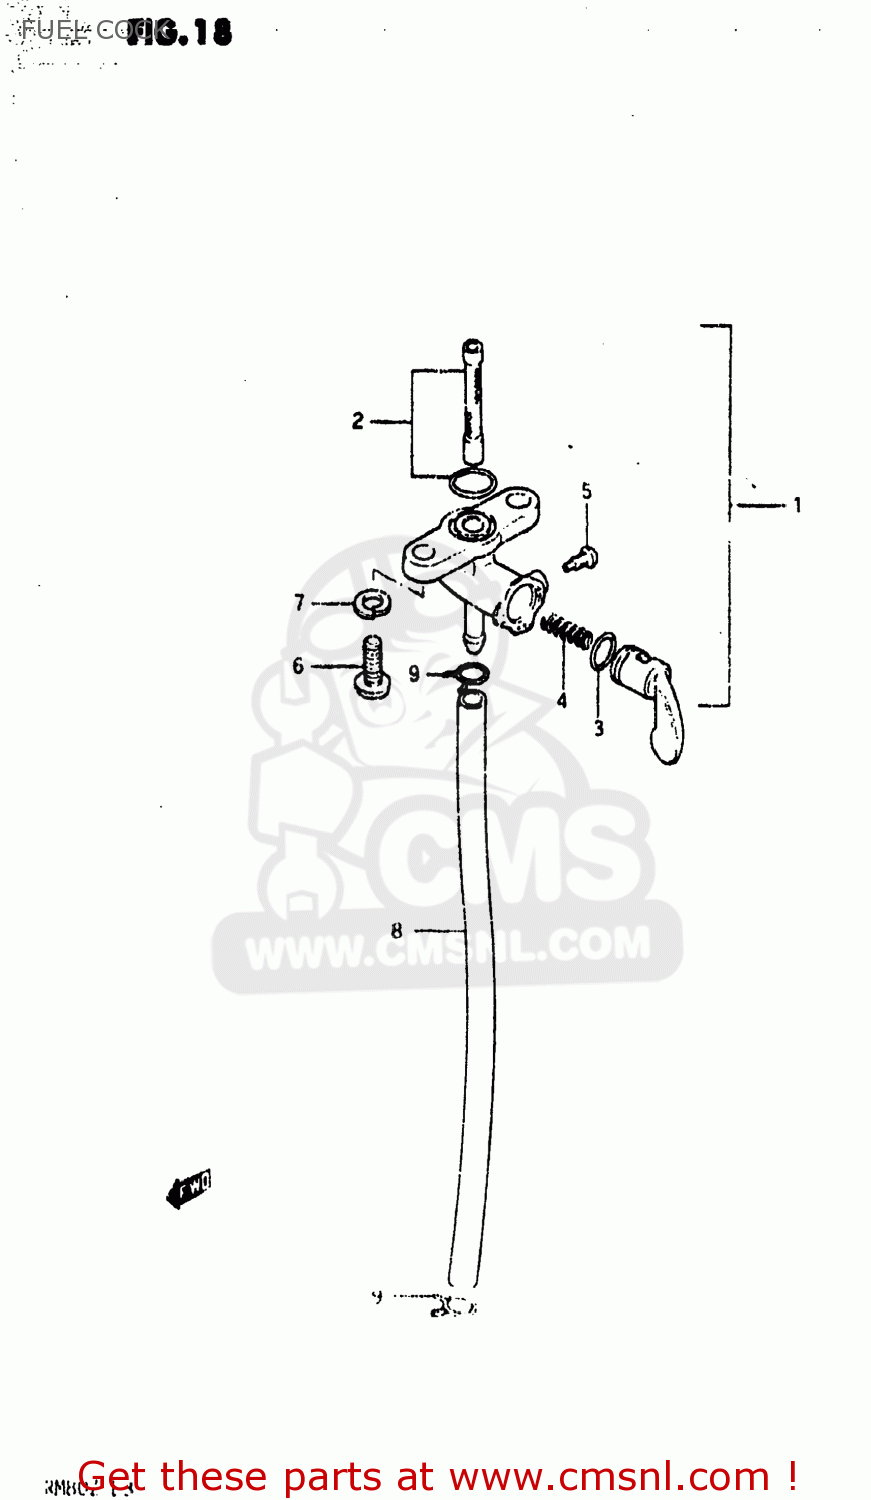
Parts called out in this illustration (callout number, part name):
1	COCK ASSEMBLY,FUEL
2	FILTER SET FUEL
3	O RING,LEVER
4	SPRING,FUEL COCK VALUE
5	SCREW
6	SCREW
7	LOCK WASHER
8	HOSE
9	CLIP
